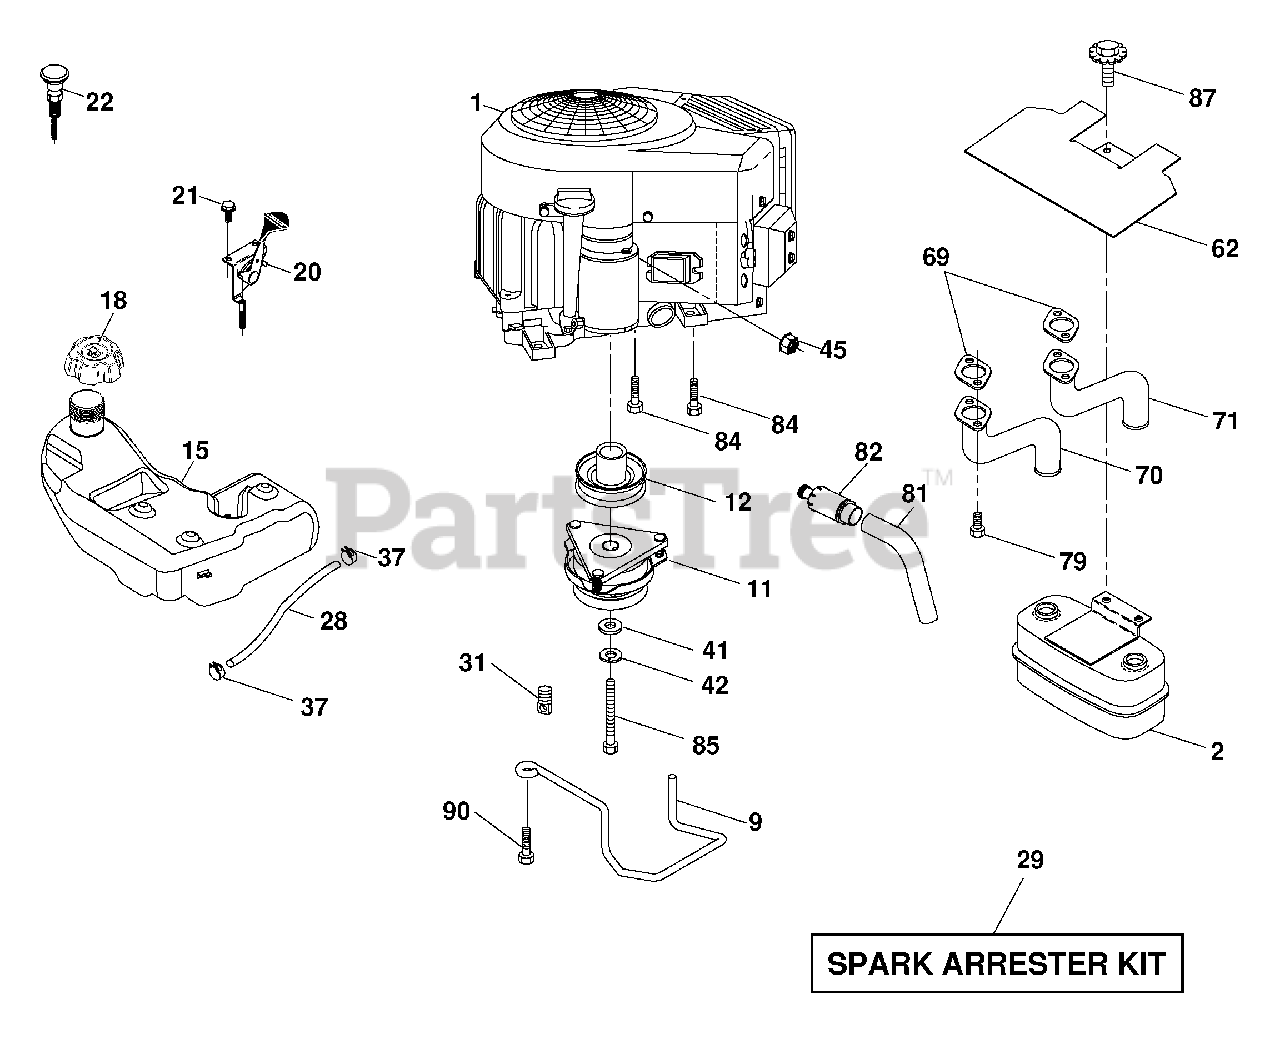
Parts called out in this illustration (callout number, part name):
2	Muffler
9	Keeper Belt Engine
11	Clutch Electric
12	Pulley Engine
15	Tank Fuel 3.0
18	Cap Asm
20	Control Throttle
21	Screw 10 x 3/4 Single Lead-Hex
22	Control Choke
28	Fuel Line
29	Spark Arrester Kit
31	Clip Push-In Hinged
37	Clamp Hose
41	Washer 1-1/2 OD x 15/32 ID x .250
42	Washer Lock 7/16
45	Nut Keps Hex 1/4-20 unc
62	Shield Heat Muffler
69	Gasket
70	Exhaust Tube RH
71	Exhaust Tube LH
79	Screw Socket Head 5/16-18 x 1
81	Tube Drain Oil Easy
82	Plug Drain Oil
84	Screw 3/8-16 x 1-1/4
85	Bolt Hex 7/16-20 x 4 x 1/4 5 Ga.
87	Bolt 5/16-18 x 3/4
90	Screw 3/8-16 x 1
